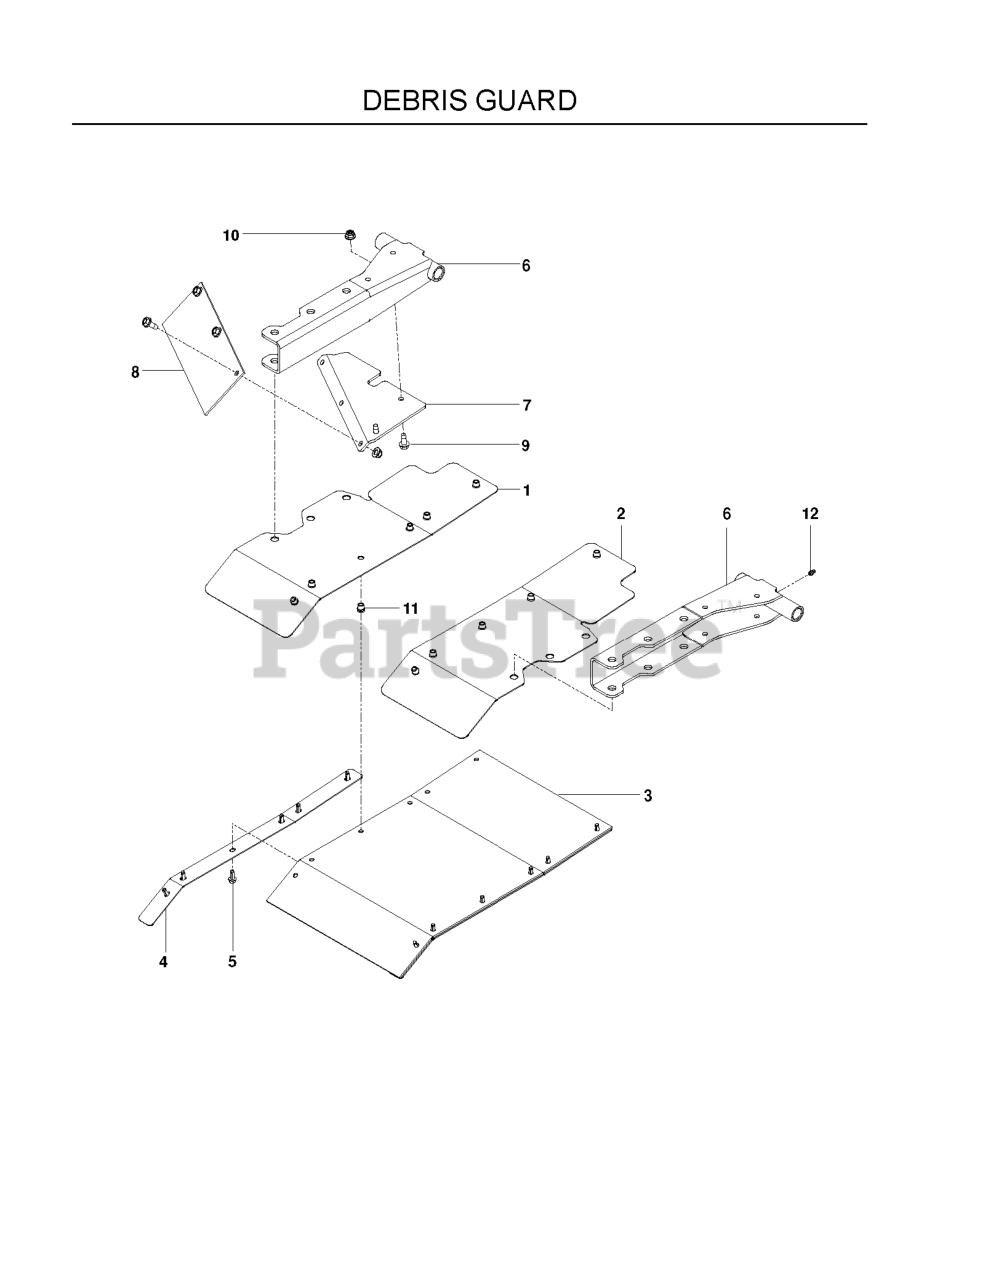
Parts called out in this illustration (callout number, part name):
1	GUARD, DEBRIS, LT, BLK
2	GUARD, DEBRIS, RT, BLK
3	GUARD, RUBBER
4	STRAP, GUARD, BLK
5	SCREW- 1/4-20 X 5/8
6	STRUT CMB BLK
8	GUARD, RUBBER, SMALL
9	BOLT 5/16-18 X 3/4
10	5/16-18 NYLOC FLANGE NUT
11	KNURLED INSERT
12	ZERK
